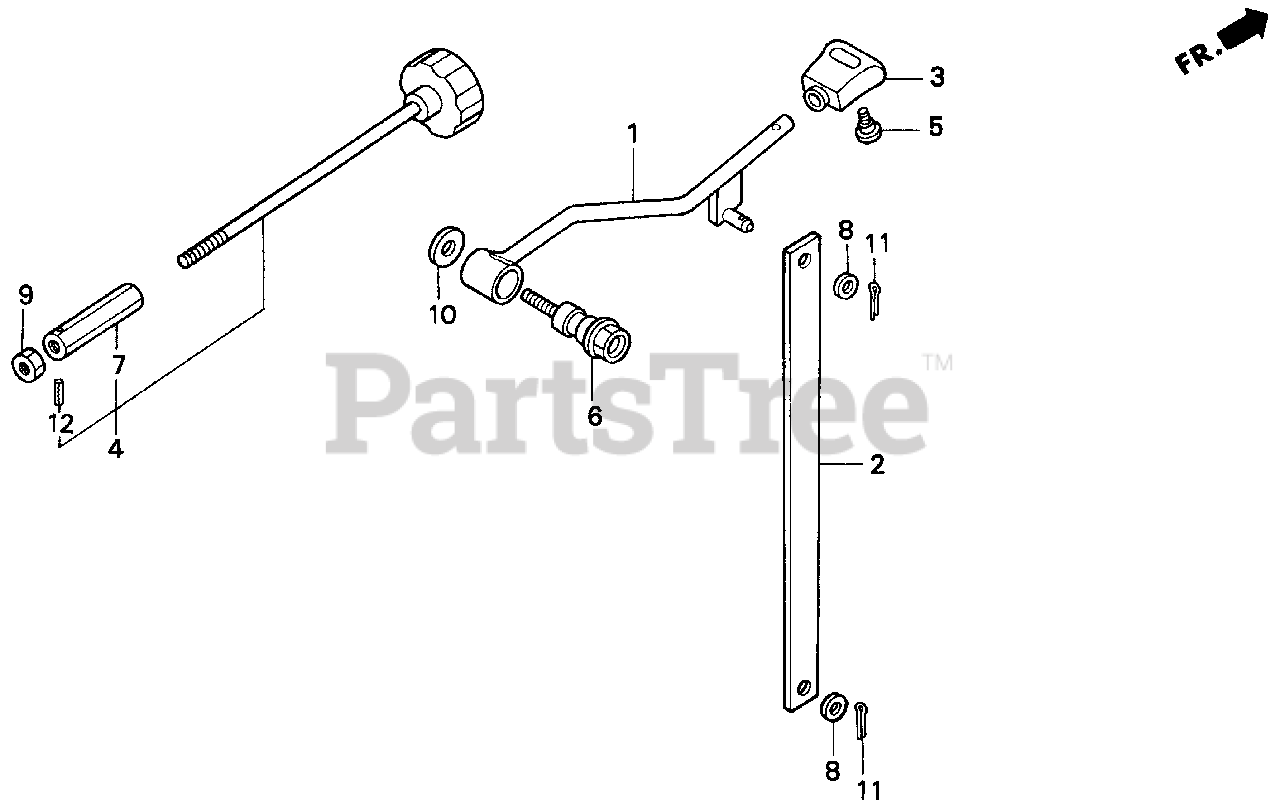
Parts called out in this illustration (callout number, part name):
1	LEVER, CHANGE (2/4WD)
2	ROD, CHANGE (2/4WD)
3	GRIP, CHANGE (2/4WD)
4	KNOB, SLOW RETURN
5	SCREW, HINGE PATCH
6	BOLT, CHANGE PIVOT
7	NUT, HEX. (8MMX40)
8	WASHER, PLAIN (6MM)
9	NUT, HEX. (8MM)
10	WASHER, PLAIN (8MM)
11	PIN, COTTER (1.6X25)
12	PIN, SPRING (3X14)
